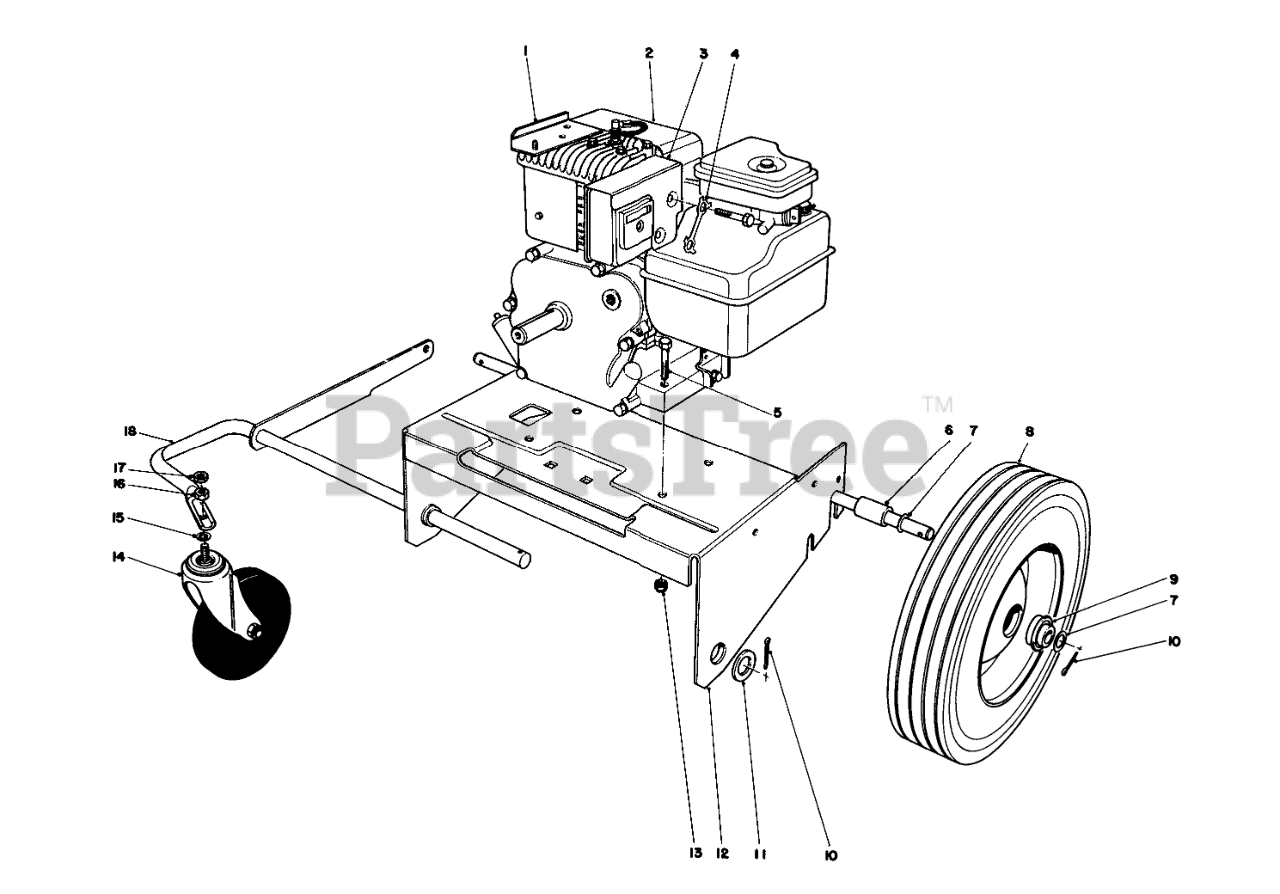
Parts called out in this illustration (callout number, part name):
1	MOUNTING BRKT WA
2	Engine
3	Heat Shield
4	Lock Strip
5	SCREW-HH
6	SPACER-AXLE
7	WASHER
8	Wheel (Incl. Ref. #9)
9	BEARING
10	PIN-COTTER
11	WASHER-FLAT
12	Engine Plate
13	NUT-LOCK, CONE
14	CASTER
15	Lockwasher
16	NUT-HH
17	1/2-13 CONELOCK NUT
18	Front Wheel Support
